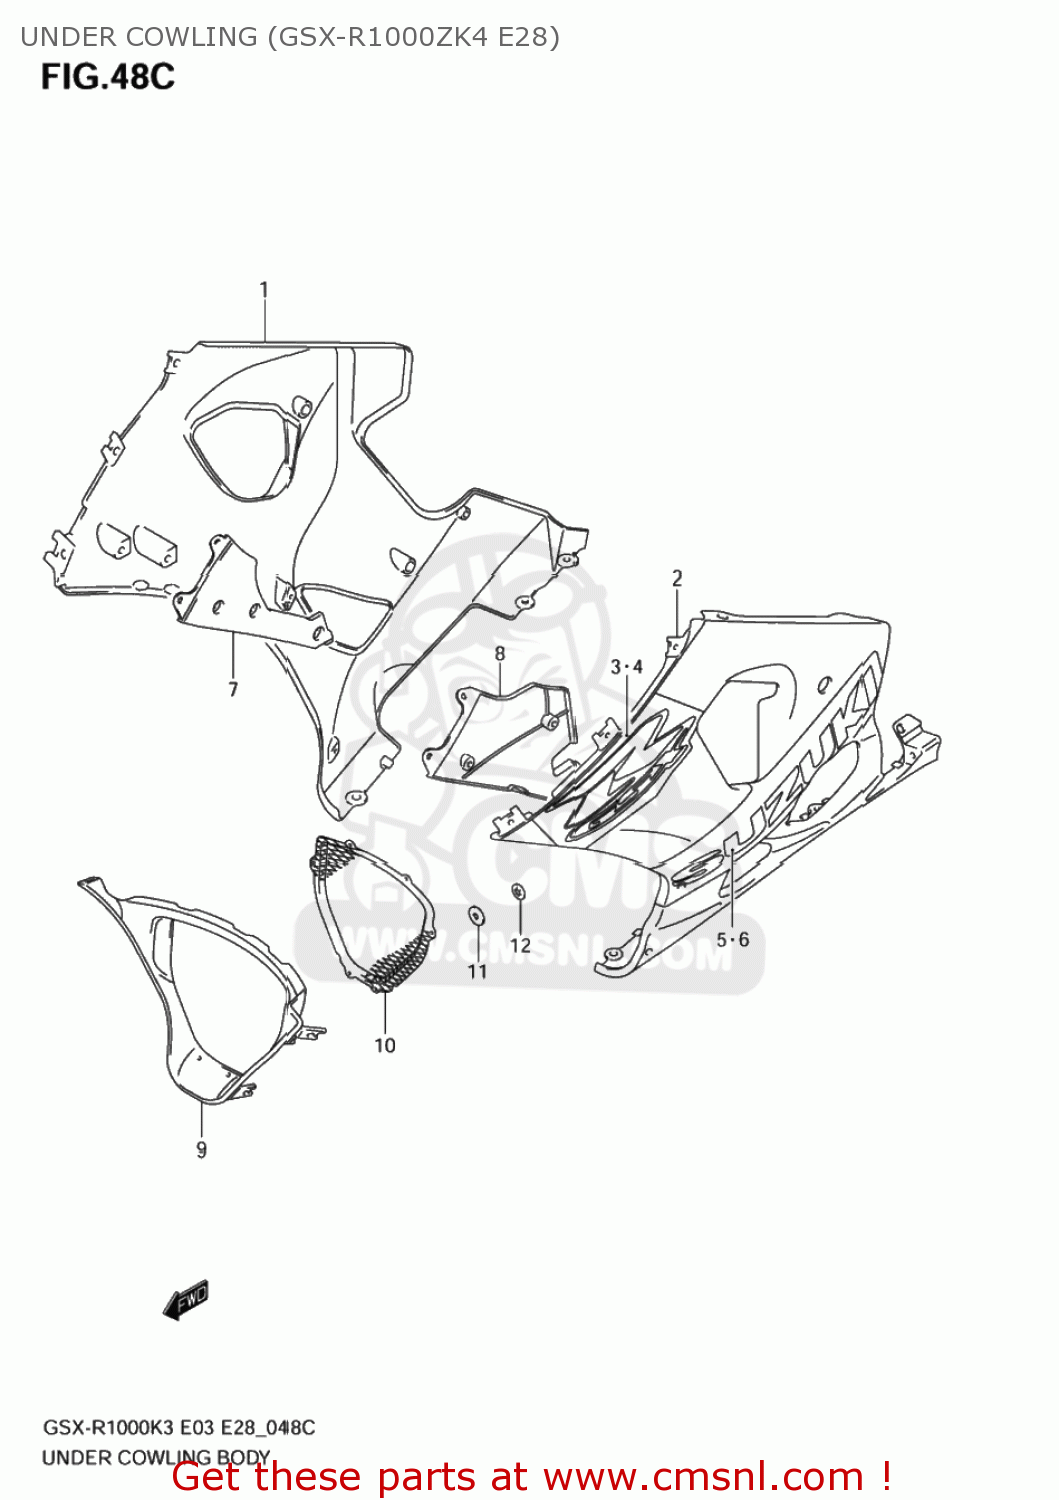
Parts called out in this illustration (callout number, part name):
1	COWLING ASSY,UNDER,R
2	COWLING ASSY,UNDER,L
3	EMBLEM,GSXR,R
4	EMBLEM,GSXR,L
5	EMBLEM,SUZUKI,R
6	EMBLEM,SUZUKI,R
7	COWLING,UNDER INNER,R
8	COWLING,UNDER INNER,L
9	COWLING,UNDER CTR
10	COWLING,UNDER CTR
11	CUSHION
12	NUT
